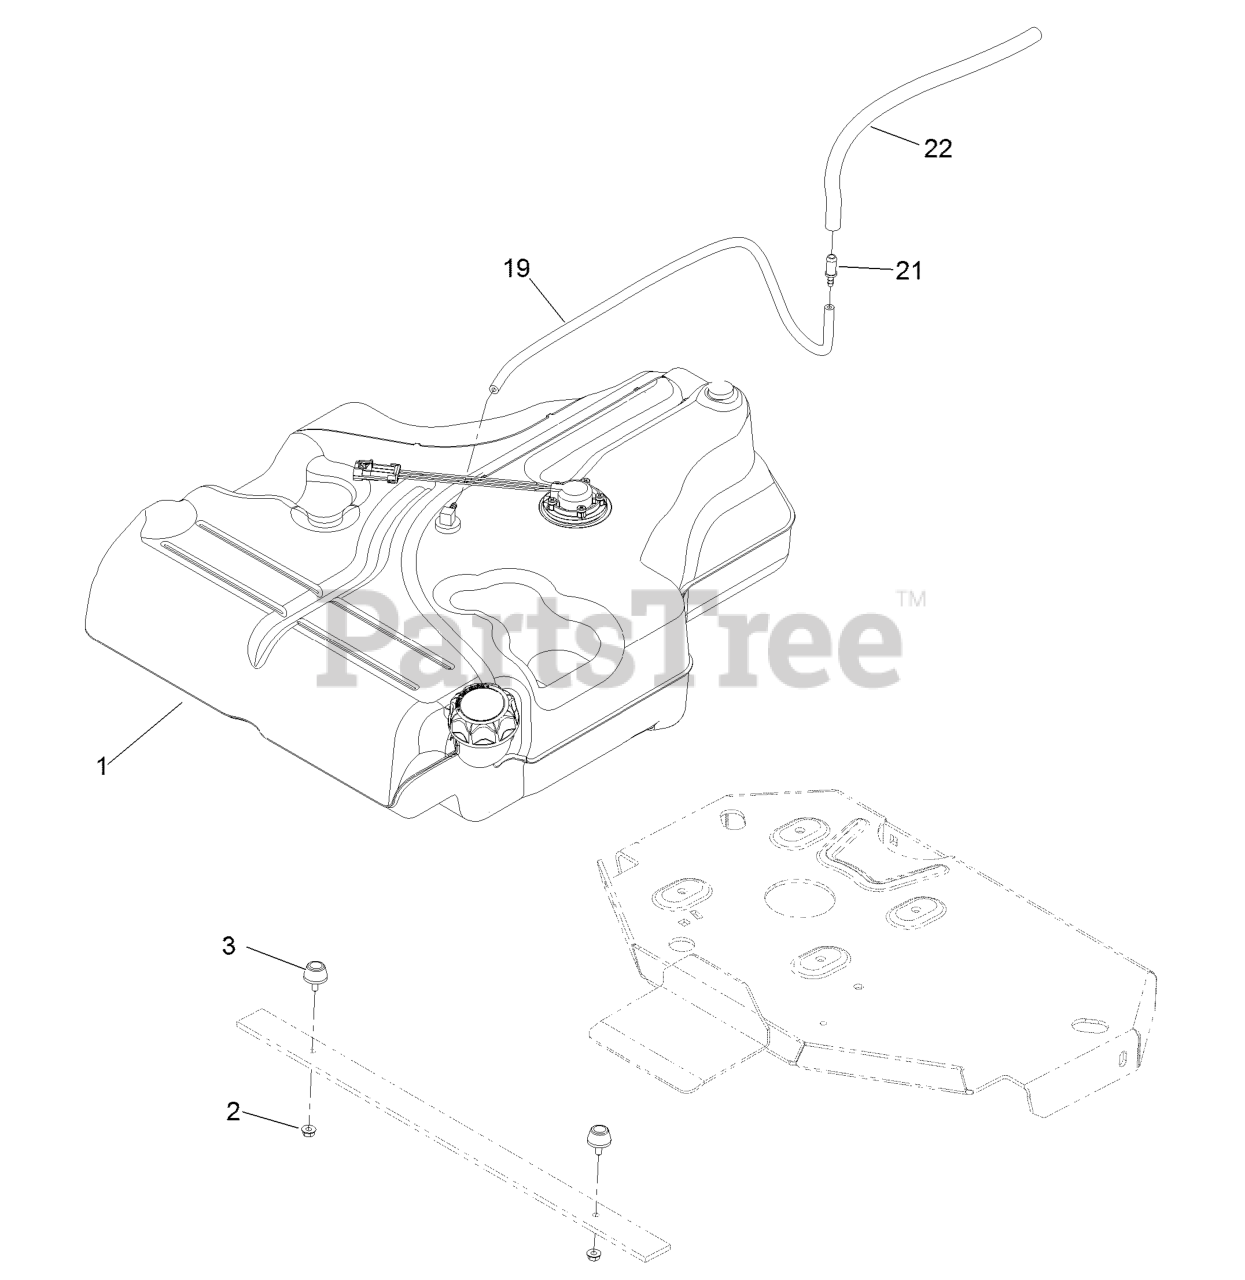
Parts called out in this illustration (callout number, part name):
2	NUT-JAM
19	HOSE-FUEL
21	FITTING-STRAIGHT
22	HOSE-FUEL
